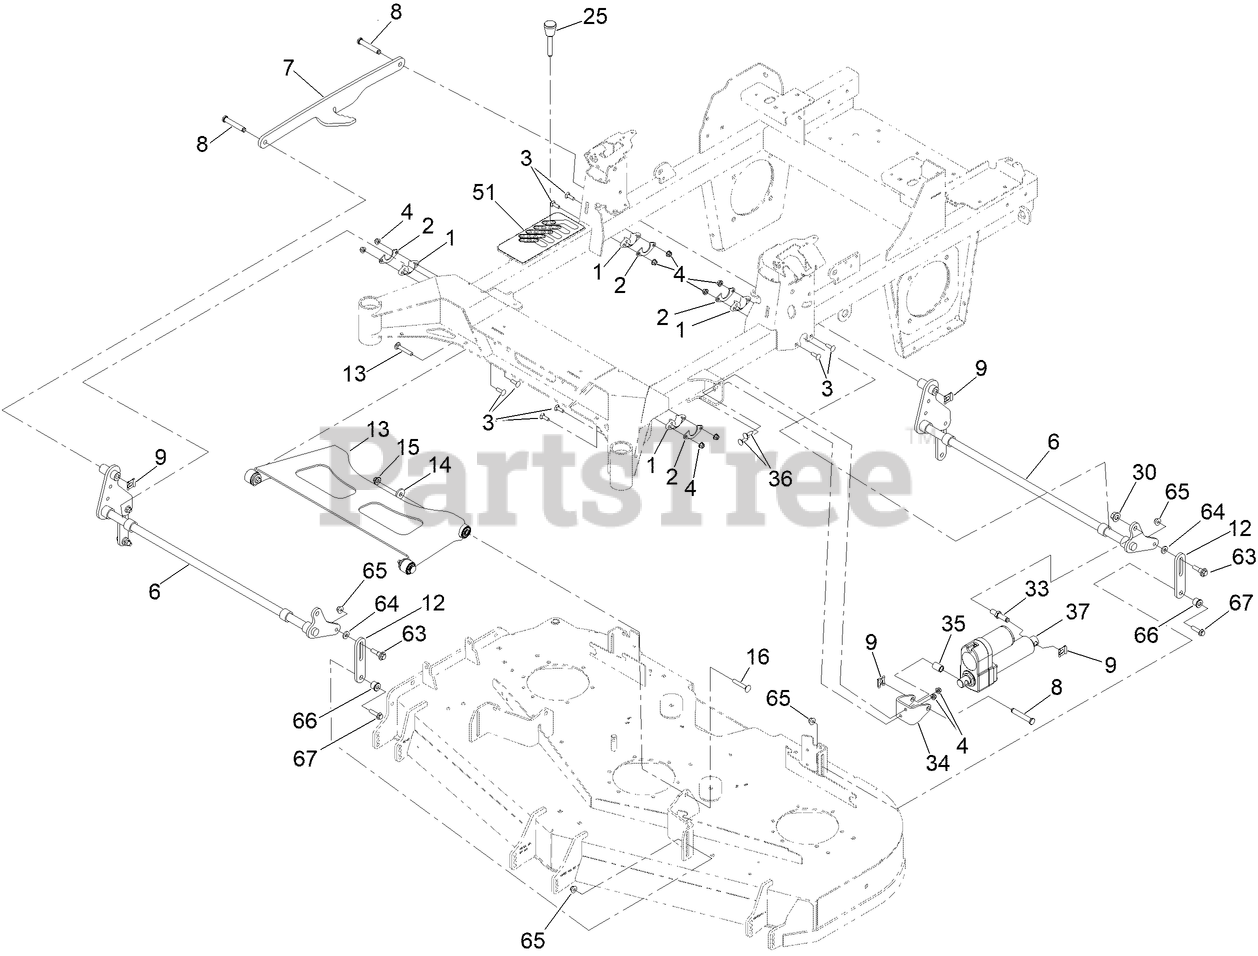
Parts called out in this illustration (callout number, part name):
1	BEARING-FLANGE
2	GUSSET-LIFT, DECK
3	SCREW-CARR
4	NUT-HF, NI
6	DECK LIFT SHAFT ASM [BLACK]
7	LINK-LIFT
8	PIN-CLEVIS
9	CLIP-PIN
12	LINK-LIFT, DECK
13	ASM-DECK STRUT W/ BUSHINGS
14	WASHER
15	NUT-FLANGE, NI
16	SCREW-CARR
25	PIN-HOC
30	NUT-LOCK
33	PIN-PIVOT, ACTUATOR
34	CYL MOUNT PLATE
35	SPACER-ALUMINUM
36	BOLT-CARR
37	ACTUATOR-LINEAR
51	DECAL-HOC
63	BOLT-SHOULDER
64	SPACER
65	NUT-HF, NI
66	BUSHING-DECK LIFT
67	SCREW-HHF
